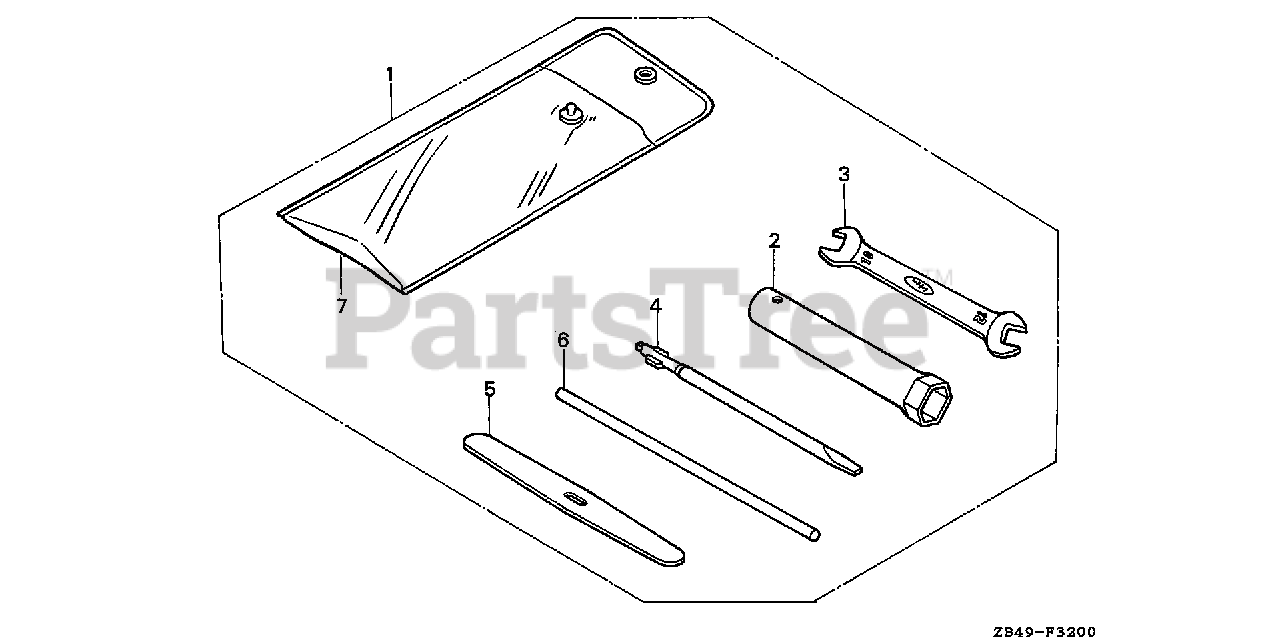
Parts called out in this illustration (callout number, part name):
1	TOOL KIT (NOT AVAILABLE)
2	WRENCH, BOX (P21)
3	SPANNER (10X12)
4	DRIVER 3, MINUS SCREW (NO.2)
6	BAR A, HANDLE
